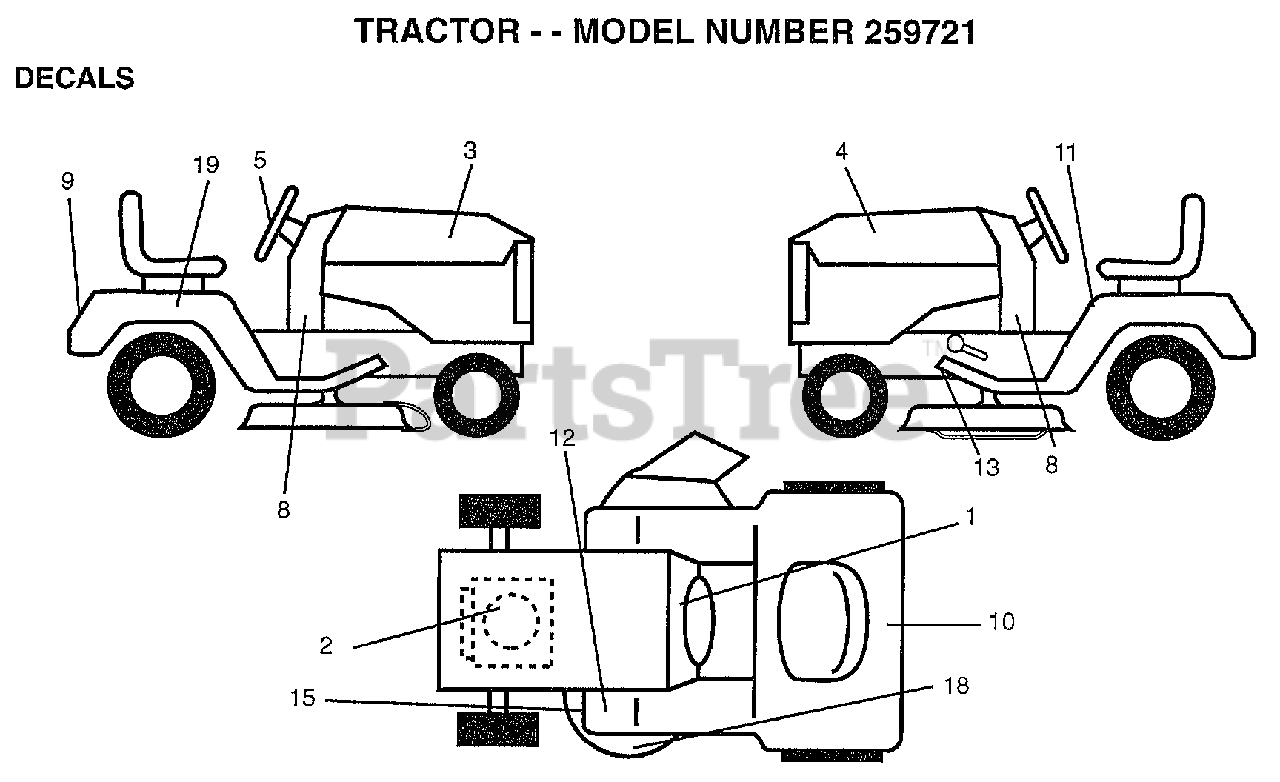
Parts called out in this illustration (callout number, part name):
1	"DECAL DASH,OPER."
2	DECAL HP ENGINE
3	DEECAL.HOOD.RH
4	DECAL.HOOD.LH
5	DECAL, INS STRG WH
8	DECAL.PNL.SD
9	DECAL.FENDER.LOGO
10	DECAL.BATRY.3-3908
11	"DECAL-FENDER,DANG"
15	DECAL
18	DECAL.MOWER.HOME
21	DECAL, GRILLE LENS
